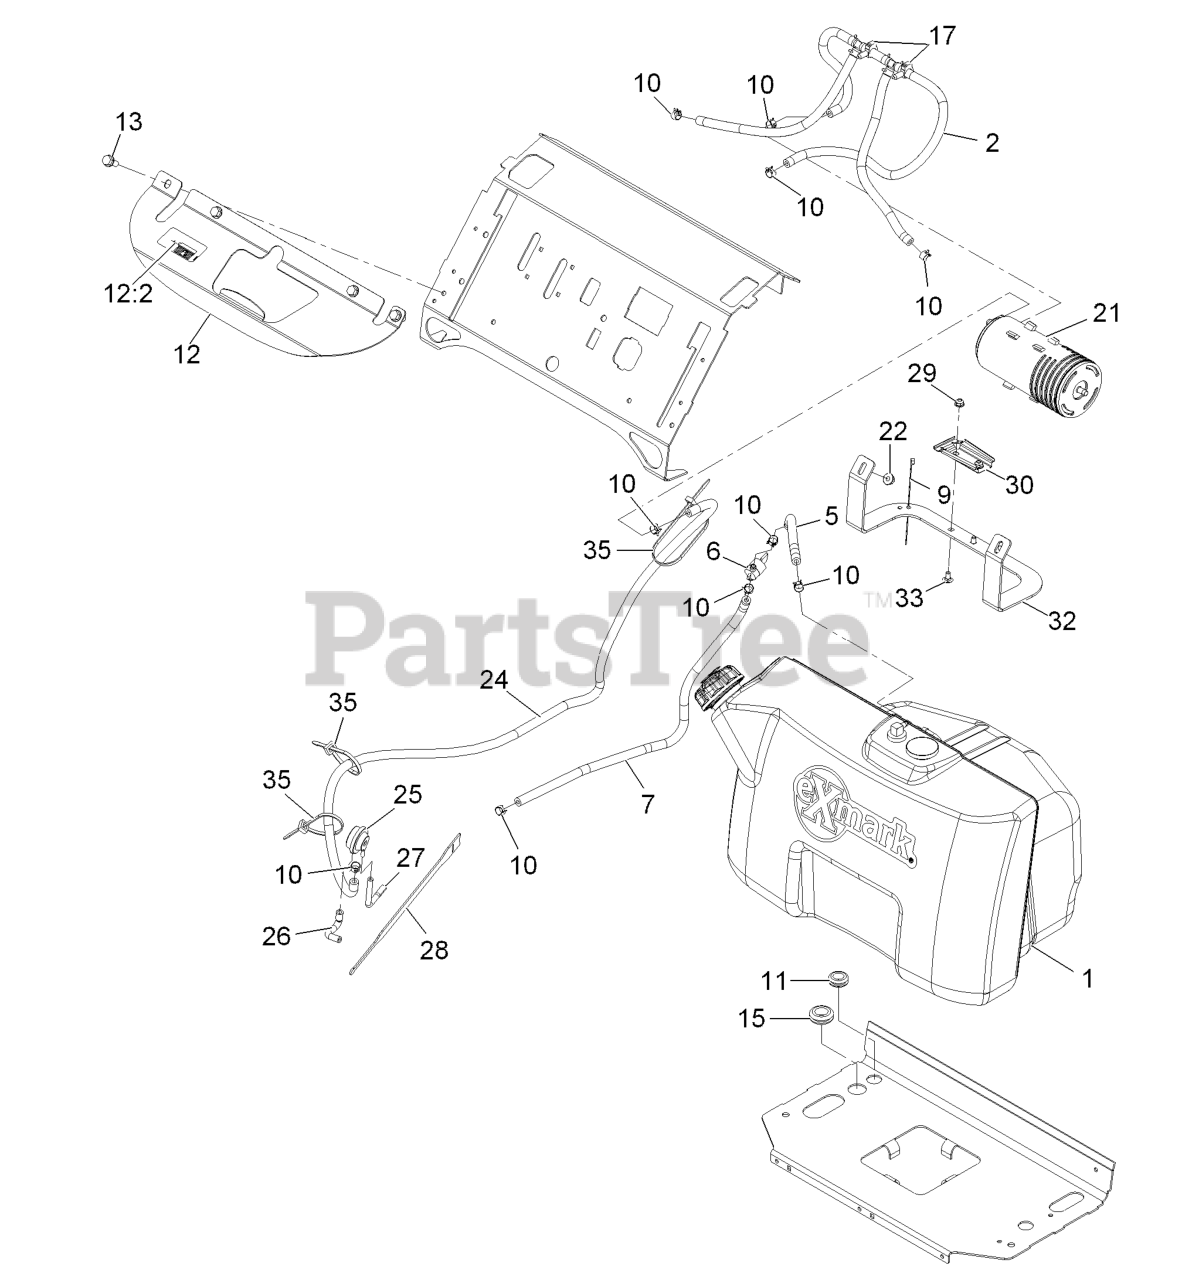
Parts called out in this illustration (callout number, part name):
2	VENT ASM
5	HOSE-FUEL
6	VALVE-FUEL
7	HOSE-FUEL
9	TIE-CABLE
10	CLAMP-HOSE
11	GROMMET
12	BRACKET-TANK
12:2	DECAL-FILL, FUEL
13	SCREW-THD ROLL, HWH
15	GROMMET
17	CLIP-HARNESS
21	CANISTER-CARBON, 800CC
22	NUT-HF, NI
24	HOSE-FUEL
25	VALVE-CONTROL, VACUUM
26	HOSE-VENT, FORMED
27	HOSE-VENT, FORMED
28	STRAP-VELCRO, CABLE TIE
30	BRACKET-CANISTER, CARBON
32	BRACKET,CANISTER MOUNTING
33	SCREW-CARR
35	TIE-CABLE
